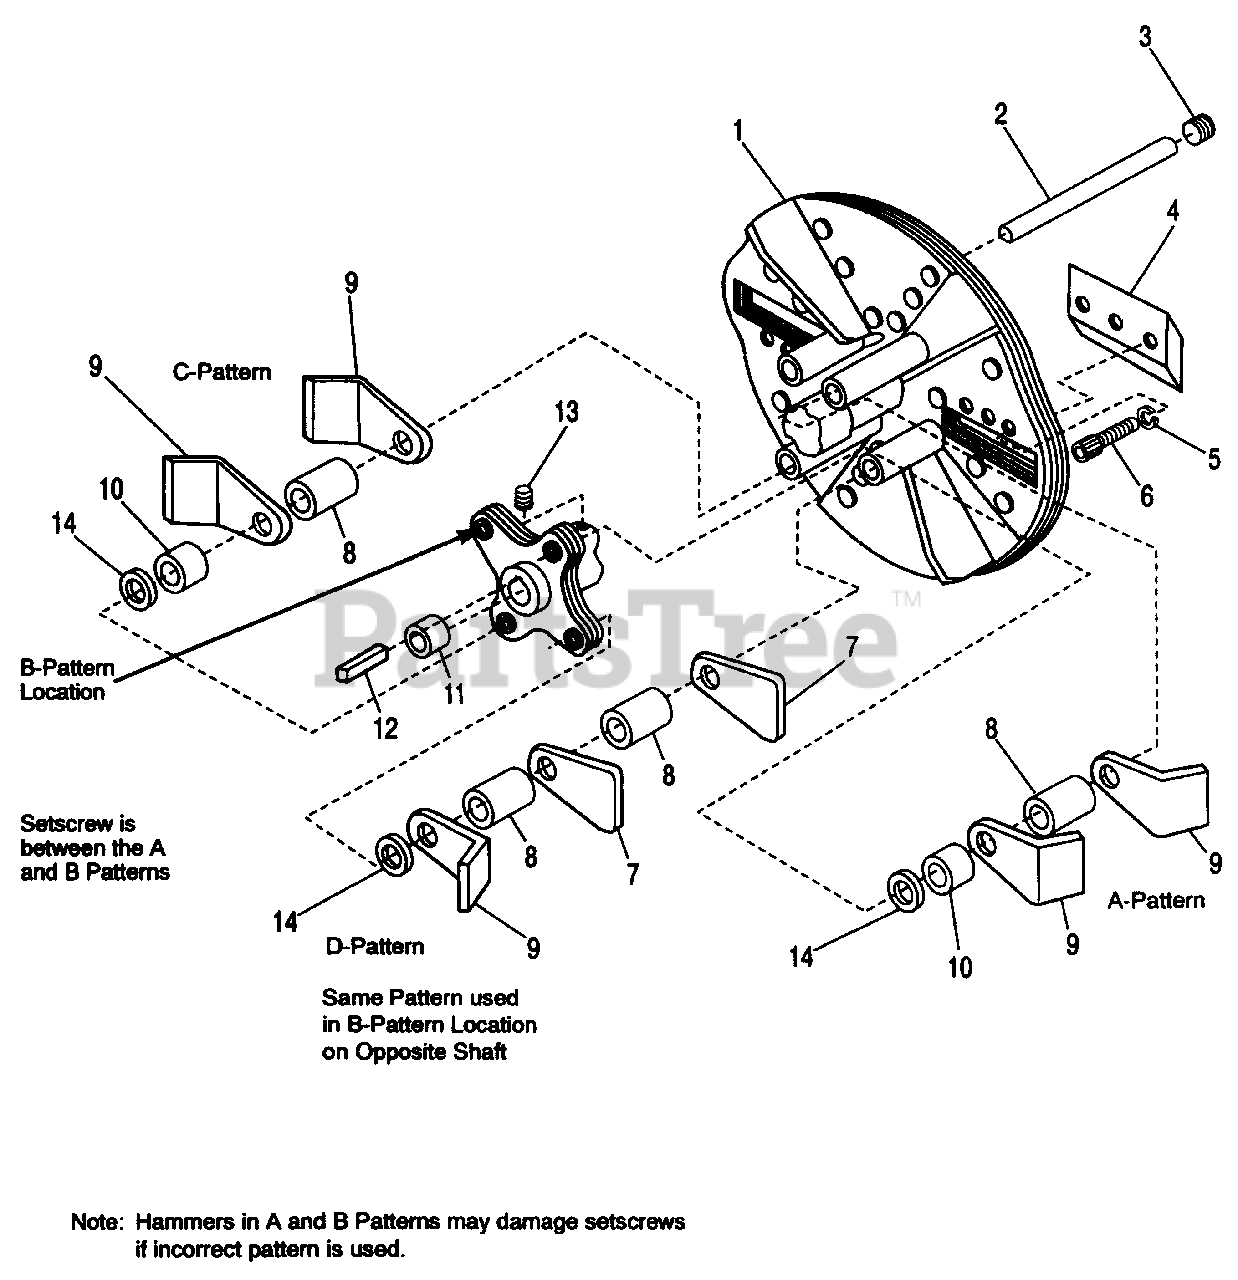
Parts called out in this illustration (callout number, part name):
1	ROTOR (PTO)
1	ROTOR (Trailer)
2	SHAFT, Hammer
3	PIPE Plug, Socket Head, 1/2"
4	KNIFE, 5"
5	LOCKWASHER, 1/2"
6	CAPSCREW, Socket Hd., 1/2-20 x 1-5/8
7	HAMMER, Triangular
8	SPACER, Long, 1-7/8"
10	SPACER, Short, 1"
11	SPACER, (PTO)
12	KEY, 3/8 x 3-3/8 (Trailer)
12	KEY, 8 mm x 56 mm (PTO)
13	SCREW, Set, 1/2-20 x 1/2 (Apply Loctite)
14	WASHER, 3/4 I.D. x 1-39/64 O.D. x 3/64 THK.
